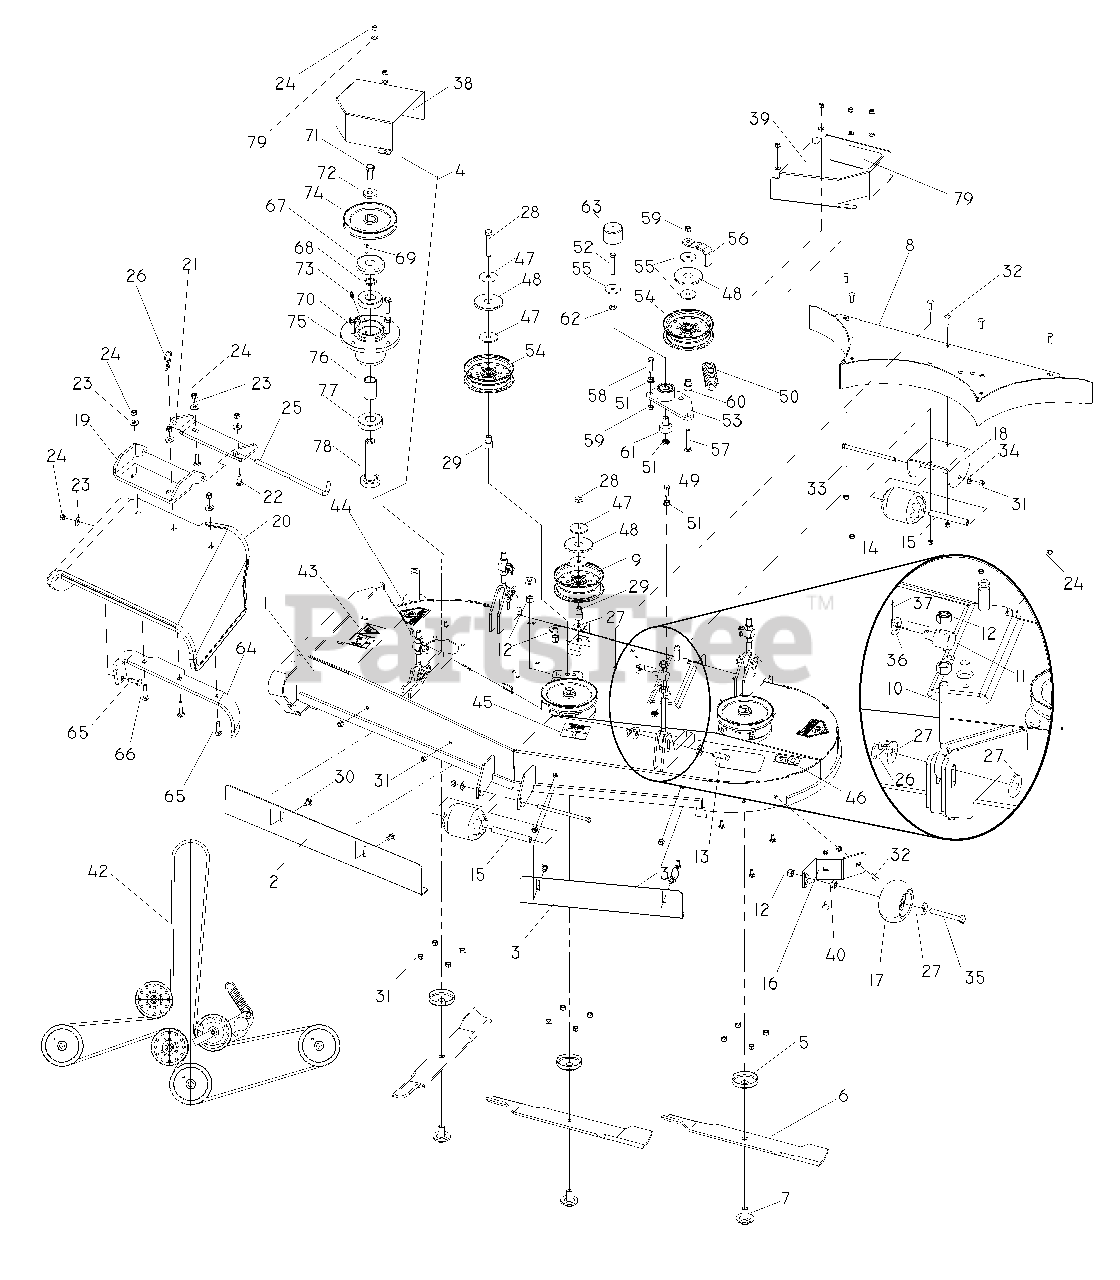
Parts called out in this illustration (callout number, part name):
1	DECK W/DECAL 60" KODIAK
2	BLOW BY BAFFLE
3	BLOW BY BAFFLE LH 60
4	SPINDLE ASSEMBLY
5	TRASH GUARD
6	BLD 60" HI LIFT FUSION
7	BLADE BOLT/WASHER
8	W-BAFFLE WLDT.
9	IDLER PULLEY (TALL)
10	BOLT, EYE
12	NUT 1/2-13 HEX NYLOC ZD
13	CLEVIS PIN 1/2X1-3/4LG
14	ROLLER 3-3/4 DIA. X 4-1
15	BUSHING
16	BRACKET
17	GAUGE WHEEL
18	REAR CENTER ROLLER BKT 60 BLK
19	PIVOT BRKT RUBBER CHUTE
20	CHUTE, RUBBER DISCHARGE 60"
21	PIVOT BRACKET - DECK
22	RHSSNB 5/16C X 1.0
23	WASHER 5/16 FLAT
24	NUT 5/16 NYLOC
25	DEFLECTOR PIN
26	PIN, COTTER 1 3/4
27	WASH USS FLAT 1/2
28	SCREW, 1/2C X 3 HEX CAP
29	SPACER - IDLER
30	RHSNB 3/8-16 X 3/4 GR5 ZD
31	NUT 3/8-16 NYLOC
32	RHSSNB 5/16C X 1.0
33	3/8-16 X 6-1/2 HHB GR8
34	WASHER 3/8 FLAT
35	HCS 1/2-13 X 4 GR 5 ZD
36	WASHER 1/2" FLAT
37	PIN COTTER 1/8 X 1 ZD
38	PULLEY GUARD RH BLACK
39	PULLEY GUARD 52 LH BLACK
40	NUT HEX 1/2
41	SCREW, TAP & DR #12-14 X 3/4
42	V-BELT 170" B
43	DECAL, EURO SEVERING
44	DECAL, CPSC
45	DECAL, BELT ROUTING (18656)
46	DECAL, 60"
47	ISOLATOR WASHER
48	TOP DUST CAP
49	HCS 3/8C X 1
51	NUT 3/8C WHIZ
52	HCS 3/8C X 2 1/2
53	ARM-IDLER W/BRG
54	IDLER PULLEY
55	WASHER, 3/8 SPEC
56	GUIDE, BELT
57	RHSNB 3/8-16 X 2.75
58	HCS 3/8-16 X 1-1/2
59	NUT 3/8-16 HEX JAM
60	BUSHING, IDLER
61	PIVOT, BEARING
62	WASHER 3/8 SAE FLAT
63	CAP, VINYL
64	BRKT REINF-CHUTE 60"
65	BOLT, CARRIAGE 5/16X1-1/4
66	RHSNB 5/16-18 X 1-1/2 GR 5 ZD
67	TRASH GUARD
68	SPACER .25
69	KEY - 1/4 X .88
70	HCS 3/8C X 1 1/2
71	1/2-20 UNF X 1 1/4 HHBLT
72	WASHER .525 X 1.375 X .25
73	ZERK, 3/16, DRIVE IN
74	PULLEY 6.45 METRIC
75	DECK HUB MACHINED
77	BEARING - 6305 - 2RS
78	SHAFT SHORT
79	FLAT WASHER 5/16 SAE
79	REAR FLOOR PAD-LH
